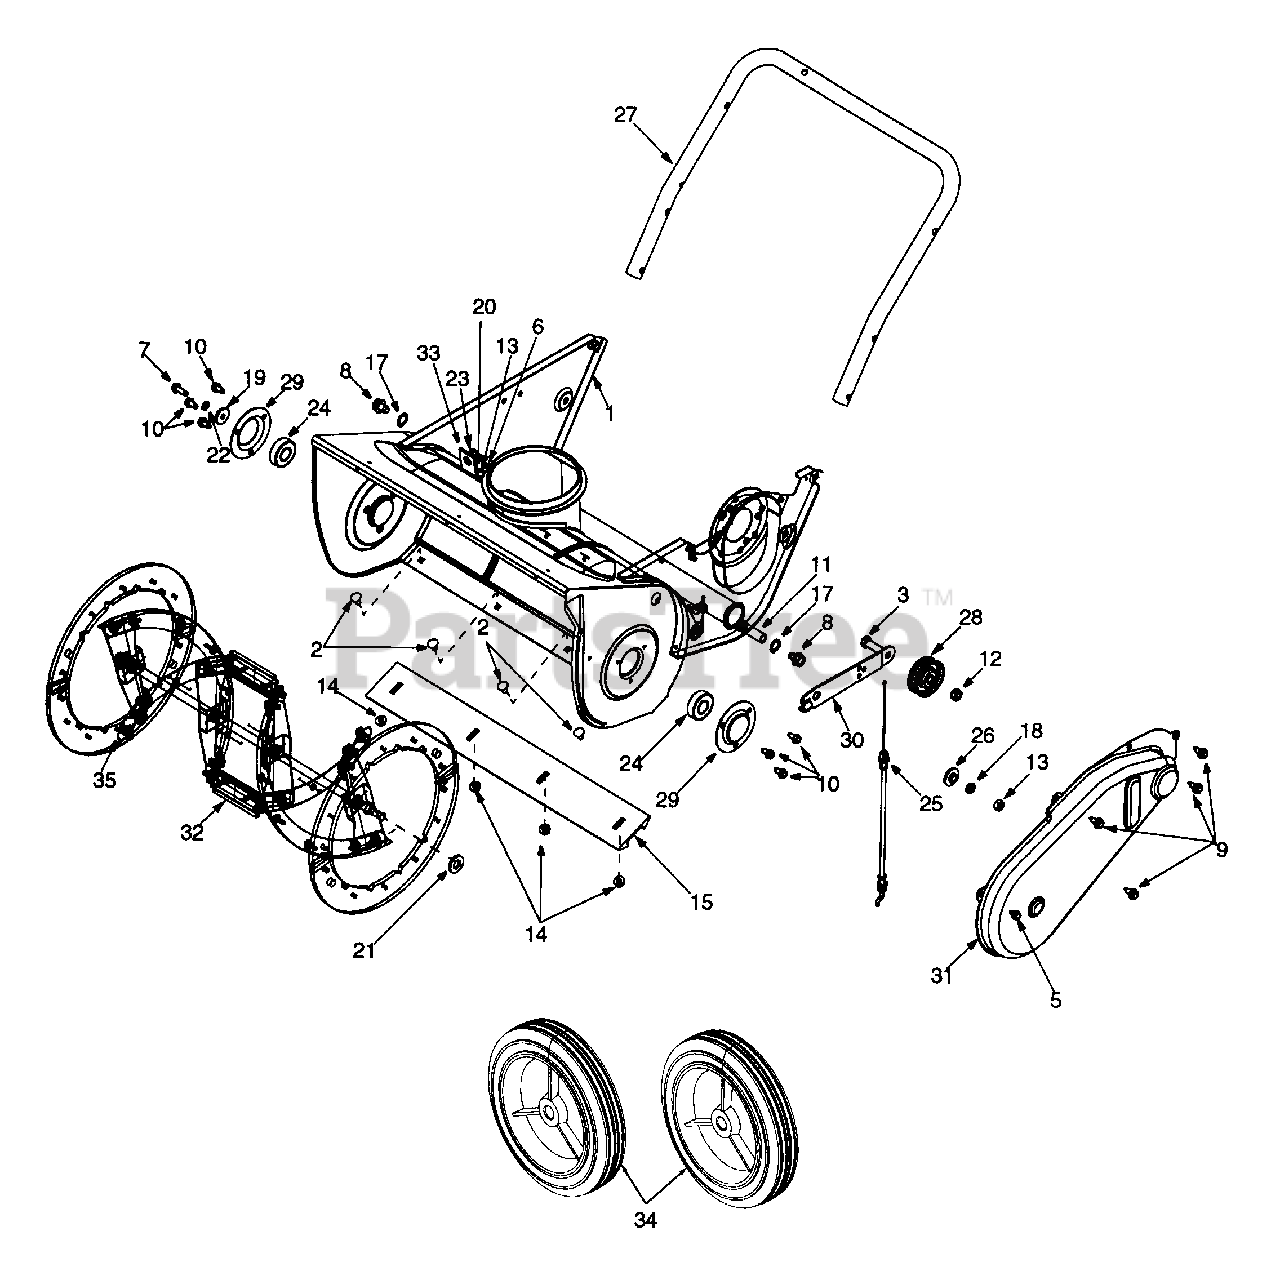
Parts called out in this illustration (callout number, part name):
3	Special Screw 3/8-24 x 1.25" Gr.8
4	Truss Mach. Screw 5/16-18 x 0.75"
5	Hex Screw 1/4-14 x 0.375"
6	Carriage Bolt 5/16-18 x 0.75"
7	Hex TT Screw 1/4-20 x 0.75"
8	Hex TT Screw 3/8-16 x 0.5"
9	AB Screw 1/4-14 x 0.625"
10	B Screw 1/4-14 x 0.5"
11	Axle Tube
12	Jam Nut
13	Hex Nut
14	Hex Flange Lock Nut
15	Shave Plate
16	Extension Spring
17	Flat Washer
18	Lock Washer
19	Flat Washer
20	Belleville Washer
21	Flat Washer
22	Lock Washer
23	Bushing
24	Ball Bearing
25	Clutch Cable
26	Spacer
27	Lower Handle
28	Idler: Flat
29	Bearing Cup
30	Idler Bracket: Brake
32	Auger Assembly
33	Bracket: Chute Crank
34	Wheel Assembly: Grey
35	Auger Rubber Replacement
